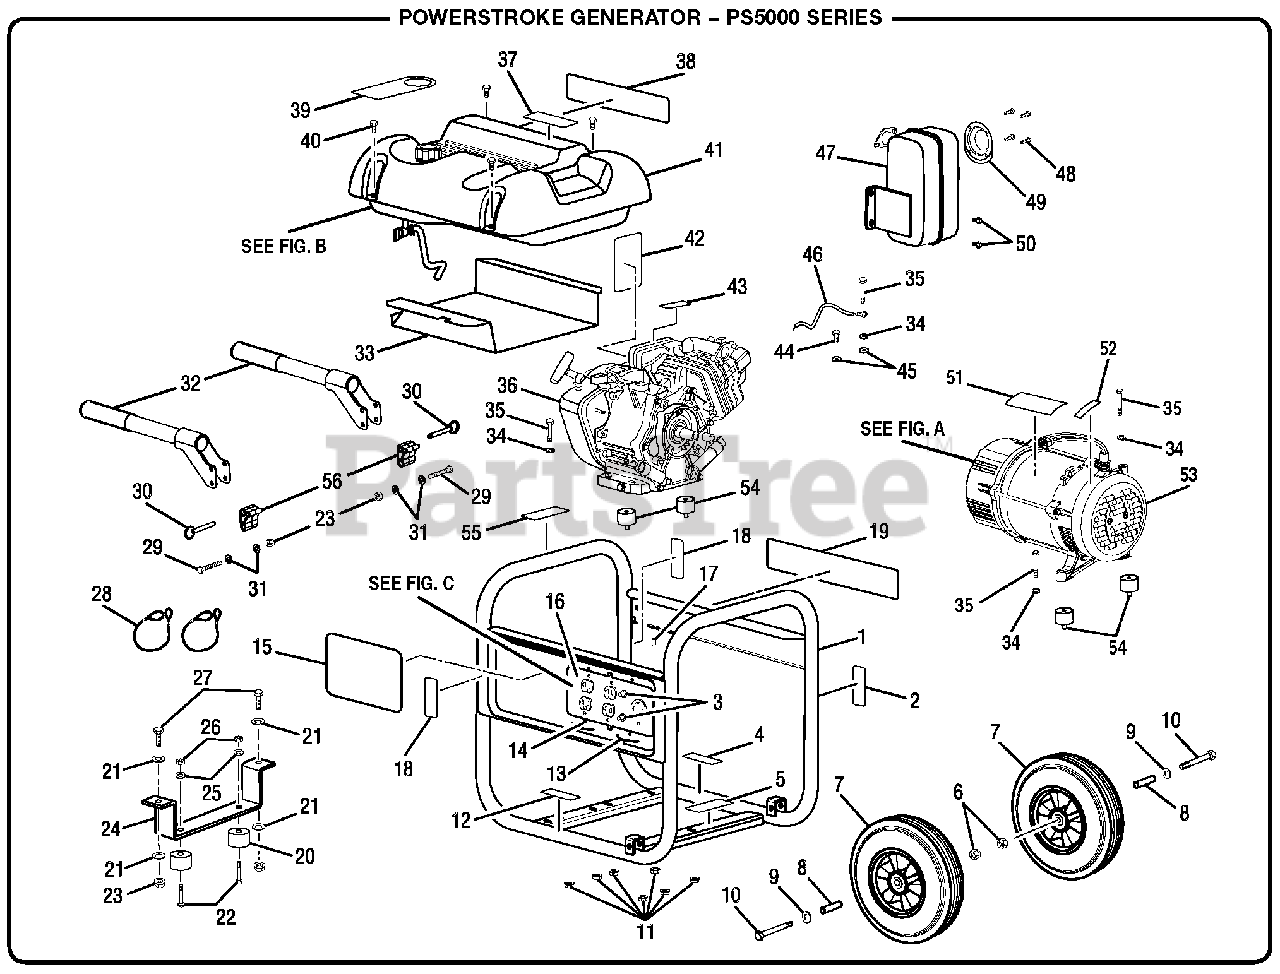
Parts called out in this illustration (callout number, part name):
1	Frame Assembly
2	Hot Surface Label
3	Circuit Breaker (20 amp)
4	Combustion Label
5	Ground Warning Label
6	Lock Nut (3/8-16)
8	Spacer (.38 ID)
9	Washer (3/8 in.)
10	Bolt (3/8-16 x 4-1/4 in.)
11	Flange Nut (5/16-18)
12	Engine Lubricant Label
13	Cord Retainer
14	Screw (6-19 x 1/2 in.)
15	Logo Label
16	Control Panel Assembly
17	Rubber Cap
18	Lock Pin Label
19	Danger Label
20	Rubber Foot
21	Washer (5/16 in.)
22	Bolt (1/4-20 x 1-1/2 in.)
23	Lock Nut (5/16-18)
24	Frame Support
25	Washer (1/4 in.)
26	Lock Nut (1/4-20)
27	Bolt (5/16-18 x 1 in.)
29	Bolt (5/16-18 x 2-1/4 in.)
30	Handle Lock Pin
31	Washer (5/16 in.)
32	Handle Assembly
33	Heat Shield
34	Lock Washer (5/16 in.)
35	Bolt (5/16-18 x 1-1/2 in.)
36	Engine (Subaru OHC)
37	CPSC Label
38	Quick Start Label
39	Caution/Danger Hang Tag
40	Screw (#10 x 1 in.)
41	Fuel Tank Assembly
42	Start Label
43	Choke Label
44	Bolt (5/16-18 x 3/4 in., Hex. Hd.)
45	Washer (5/16 in.) External Star
46	Ground Wire Assembly
48	Screw (8-32 x 3/8 in.)
49	Spark Arrester Screen
50	Bolt (5/16-24 x 5/8 in.)
51	Data Label
52	Ground Label
53	Generator Head Assembly
55	Fire Danger Label
56	Handle Lock Bracket
